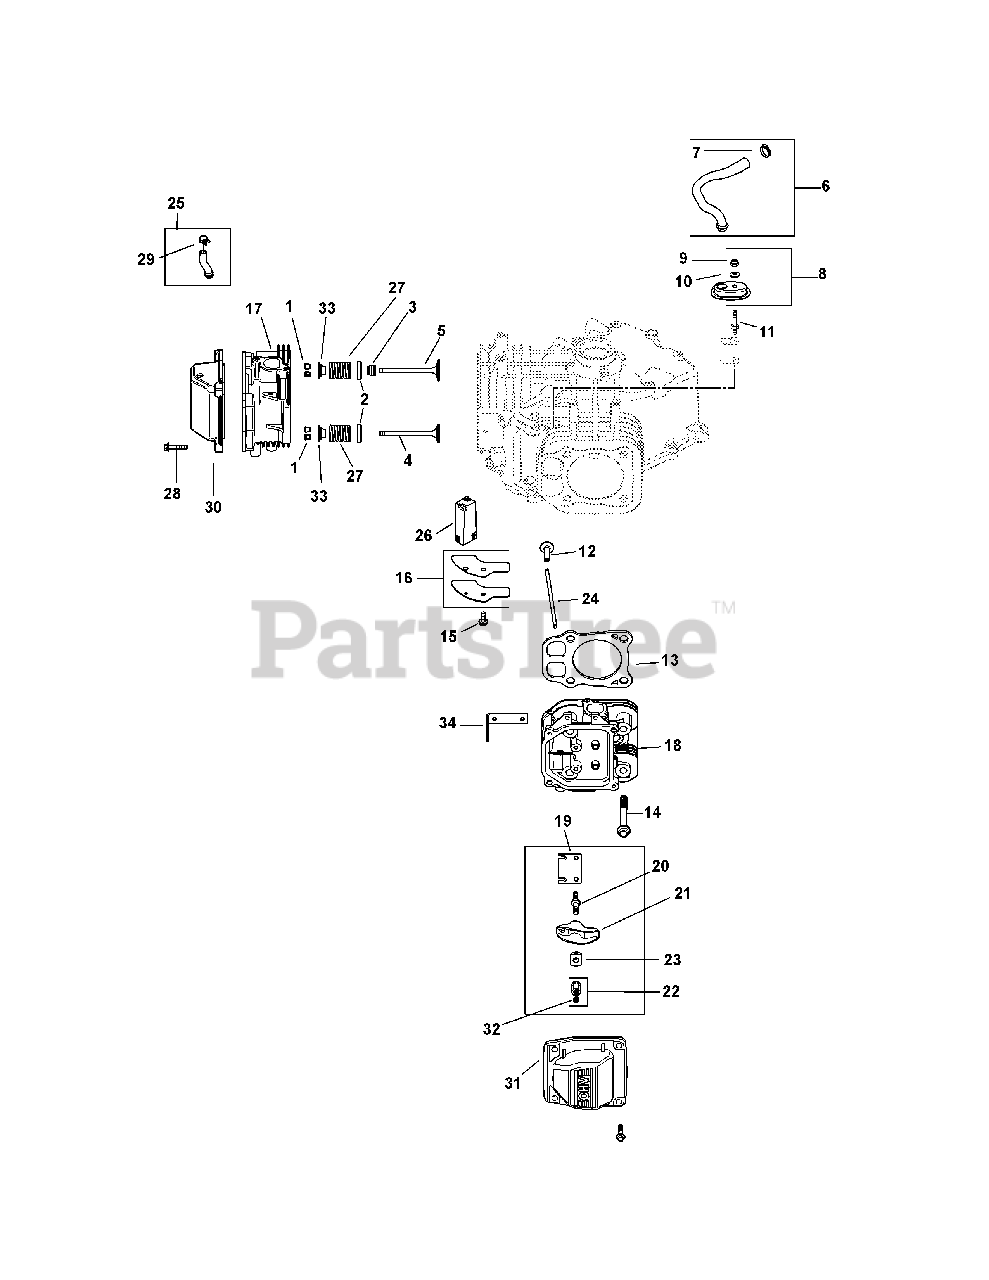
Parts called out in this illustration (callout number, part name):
1	Retainer Kit
2	Spring Retainer
3	Valve Stem Seal
4	Exhaust Valve (STD)
5	Intake Valve (STD)
6	Breather Hose Kit (Inc. #7)
7	Hose Clamp, 1/2
8	Housing Breather Kit (Inc. #9 & 10)
9	Lock Nut, M5 x 8
10	Sealing Washer
11	Breather Cover Stud
13	Cylinder Head Gasket Kit
14	Flange Screw, M10 x 1.5 x 90
15	Flange Screw, M6 x 1.0 x 16
16	Breather Cover
17	Cylinder Head Assembly Kit, #1
18	Cylinder Head Assembly Kit, #2
22	Hex Nut Assembly (Inc. #35)
23	Rocker Arm Pivot
25	Fuel Pump Hose Kit (Inc. #29)
26	Breather Filter
27	Valve Spring
28	Pan Head Screw
30	Rocker Cover
33	Valve Spring Cap
34	Lifting Strap
